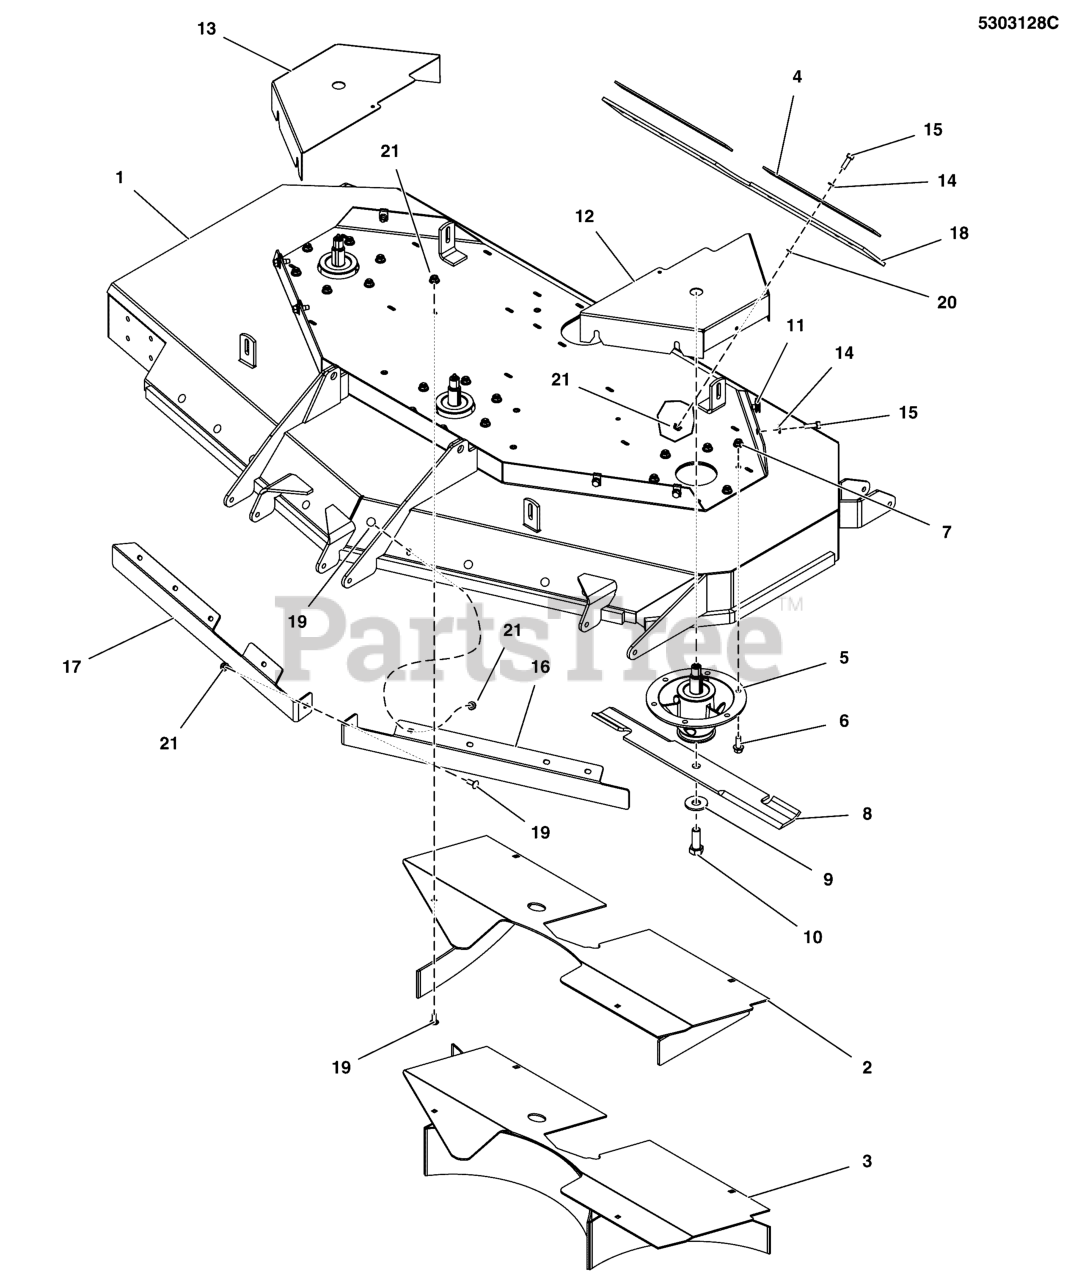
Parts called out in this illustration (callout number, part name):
1	DECK SHELL W/ DECALS, S800X, 61RDCE (5410093B)
2	WELD, REAR DIVERTER, 61 RD - RED
3	WELD, REAR BAFFLE, 61 RD - RED
4	PLATE, SUPPORT, S800X, 61RD - RED
5	SPINDLE ASSM, CAST IRON 8.0 - 6-BOLT
6	BOLT, 3/8-16 X 1, FLANGE, GD 5, CZ
7	NUT, 3/8-16 HEX NYLOCK FLANGE
8	BLADE SET, 61 DECK (3)
9	WASHER, BLADE BOLT, 9/16" F436, CZ
10	BOLT, 5/8-11 X 1-3/4 GR8
11	BODY CLIP, 5/16-18-7GA MATERIAL
12	GUARD, 61", LH - OUTFRONT - RED
13	GUARD, 61", RH - OUTFRONT - RED
14	WASHER, 5/16" SAE
15	BOLT, 5/16-18, GD5
16	BAFFLE, BLOWOUT, 61 ICD, LH - BLK
17	BAFFLE, BLOWOUT, S800XY, RH - BLK
18	FLAP, STRIPER, 61RD, F800X
19	CARRIAGE BOLT 5/16-18 X 3/4
20	5/16" PUSH-ON NUT RETAINER, STL, CZ
21	NUT, 5/16-18 HEX NYLOCK FLANGE
